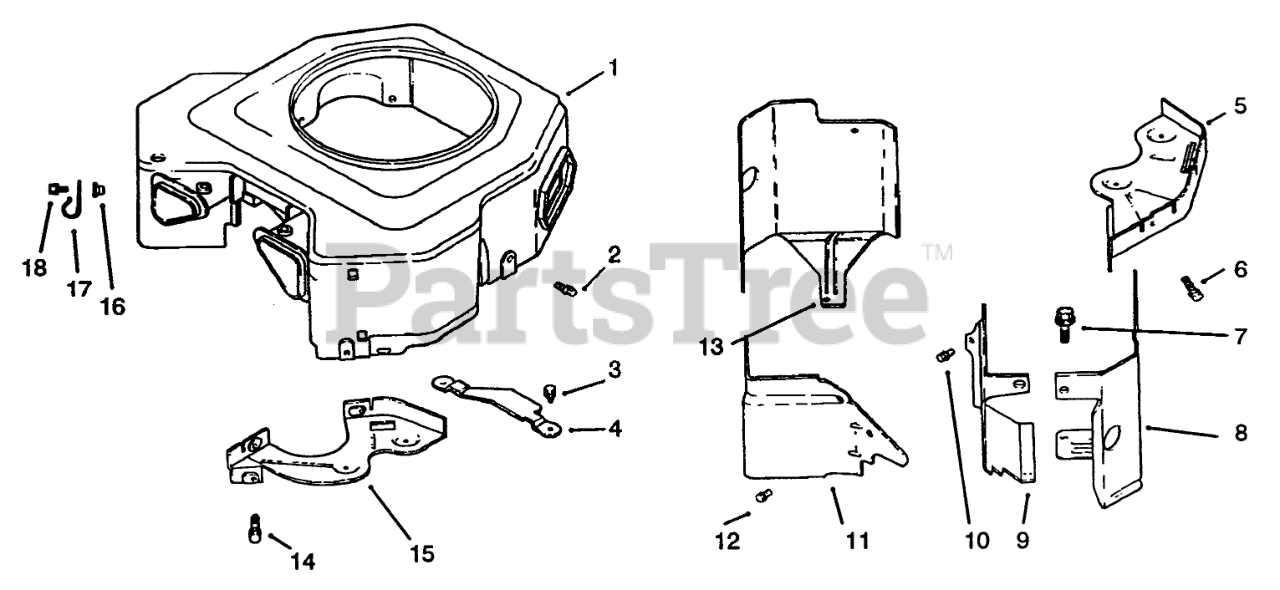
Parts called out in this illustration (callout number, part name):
1	Housing-Blower ASM (Only C)n: 72103, 72083)
2	Screw M5x0.8x16 (Only On: 72103, 72083)
3	Screw M6x1.0x16 (Only On: 72103, 72083)
4	Guard-Flywheel (Only On: 72103, 72083)
5	Plate-Backing #2 Side (Only On: 72103, 72083)
6	Screw M5x0.8x20 (Only On: 72103, 72083)
7	Screw M5x0.8x14 (Only On: 72103, 72083)
8	Baffle-Cylinder #2 Side (Only On: 72103, 72083)
9	Baffle-Valley #1 Side (Only On: 72103, 72083)
10	Screw M5x0.8x10 (Only On: 72103, 72083)
11	Baffle-Valley #2 Side (Only On: 72103, 72083)
12	Screw M5x0.8x16 (Only On: 72103, 72083)
13	Baffle-Cylinder #1 Side (Only On: 72103, 72083)
14	Screw M6x1.0x16 (Only On: 72103, 72083)
15	Plate-Backing #1 Side (Only On: 72103, 72083)
16	Nut-Plastic (Only On: 72103, 72083)
17	Clip-Cable (Only On: 72103,72083)
18	Screw-Cable Clip (Only On: 72103, 72083)
